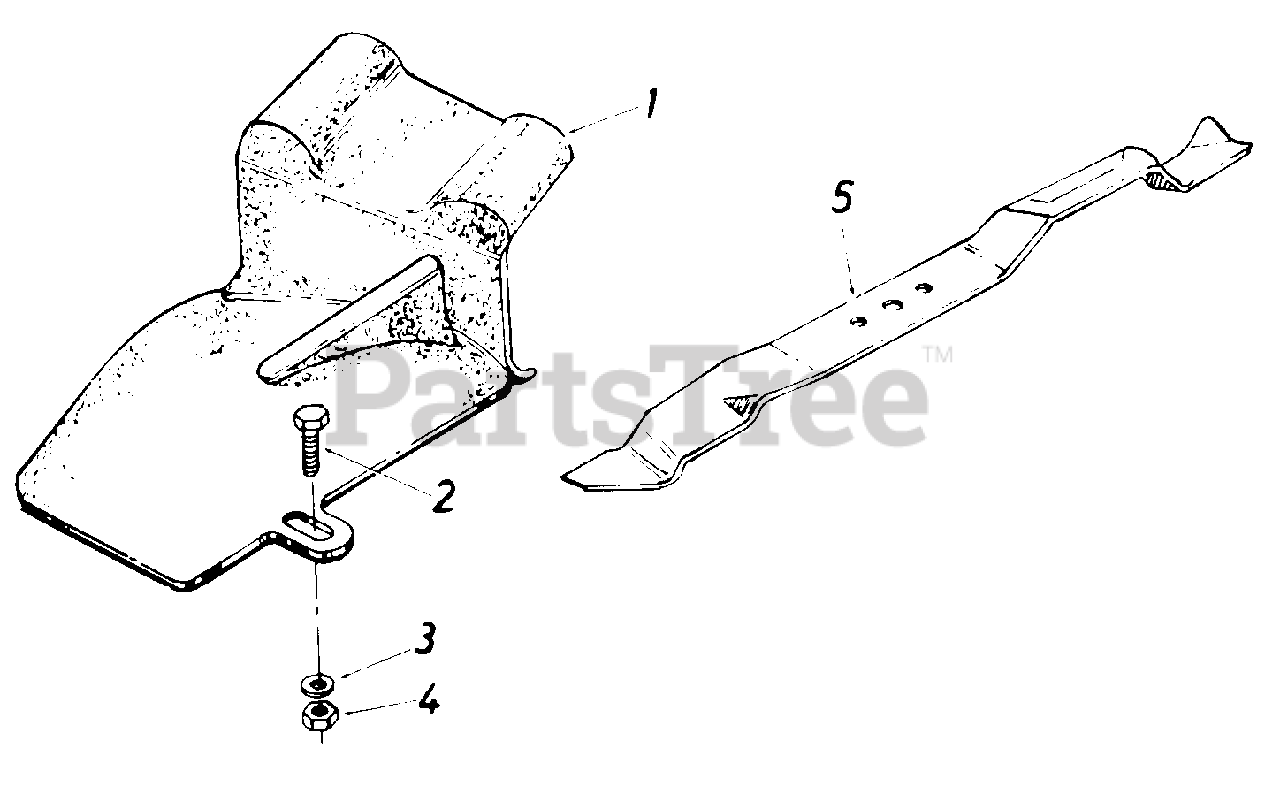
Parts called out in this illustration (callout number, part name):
1	Mulching Baffle
2	Hex Bolt 1/4-20 x .88" Lg.*
3	BelleviIle Wash. . 265 I.D. x. .75 O.D. x .093
4	Hex Jam Nut 1/4-20 Thd.
5	22" Mulching Blade
